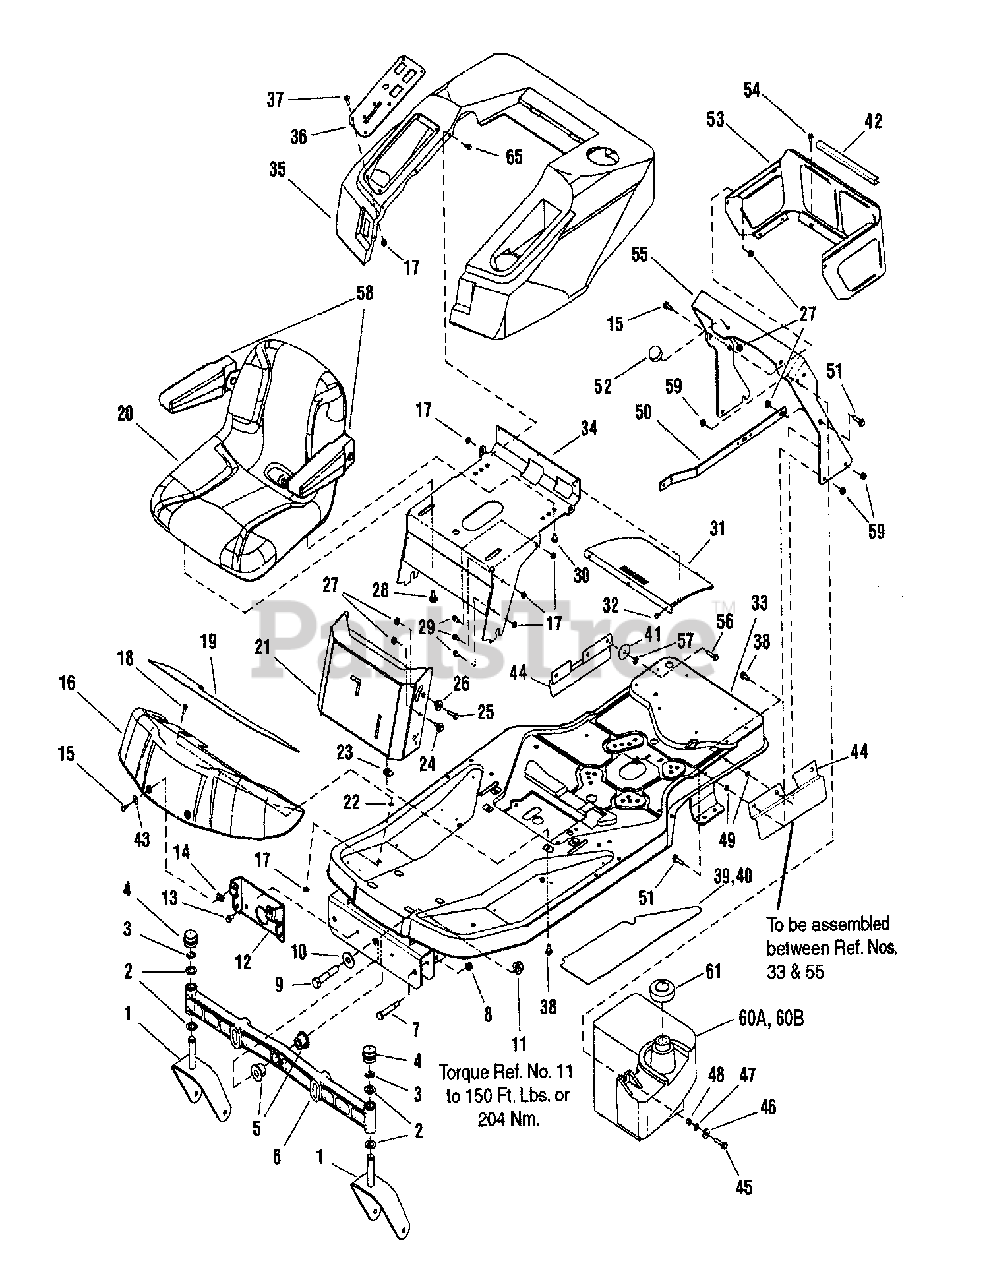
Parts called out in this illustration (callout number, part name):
1	WELDMENT, Caster Yoke & Spindle- Black
2	WASHER, .75 ID x 1.60 OD x .05 Thick Flat (Black)
3	KLIPRING, External for .750 Dia. Shaft
4	CAP, Hub 1.481 I.D. x .62 Long Red Poly
5	BUSHING, Axle Pivot PM Regent Yellow
6	AXLE, Front Iron Casting Machined ZT 2007
7	SHOULDER BOLT, 3/8-16 x 3" Long .50 Sh GR5 Black
8	NUT, 3/8-16 Hex Flange Nyloc
9	SCREW, 5/8-11 x 3-1/4" Hex Head Cap, GR5 Yellow
10	WASHER, 0.64 I.D. x 1.75 O.D. x .11 Thick, Black
11	NUT, Hex Flange 5/8-11 Two Way Lock Yellow
12	BRACKET, Footrest Support, 12 Ga Sears- Black
13	SCREW, 5/16-18 x .62 Taptite
14	SPEED NUT, 1/4-20 Lug Type .025/.150 Black
15	SCREW, 5/16-18 x 1" Hex Head Cap
16	PANEL, Footrest, 18 Ga ZT 7000 Gloss Orange
17	NUT, 1/4-20 Hex Flange Nyloc Black
18	BOLT, 1/4-20 x 2" Round Head Short Square Neck, GR5 Black
19	PAD, Footrest Center Black Vinyl Sears
20	ASSEMBLY, Seat w/Arm Rests ZTR Sears
21	PANEL, Front - Manual Brake & Deck Lift
22	RETAINER, 1/4" Bolt
23	SPEED NUT, 5/16 -18 Lug Type .025/.150 B
24	SHOULDER BOLT, 5/16-18
25	BOLT, 5/16-18 x 1-1/4" Round Head Short Square Neck GR5 Black
26	PIVOT, Hood (Powdered Metal)
27	NUT, 5/16-18 Hex Flange Lock, Small - Black
28	BOLT, 5/16-18 Idler Pivot
29	SCREW, 1/4-20 x 5/8" Hex Whiz Lock Flange
30	SCREW, 5/16-18 x 3/4" Hex Flange Lock Dog Point
31	SCREEN, Deck Top
32	RIVET, .188 x .617 Large Flange
33	WELDMENT, Frame- 33" ZT
33	WELDMENT, Frame- 42" & 50" ZT (Black)
34	SUPPORT, Seat Deck 12 GA ZTS Sears-Black
35	SEAT DECK, Orange Poly Sears ZTS
36	PLATE, Control 12 GA ZTS 2007- Black
37	SCREW, 1/4-20 x 3/4" Truss Head Torx Black
38	BOLT, 5/16-18 x 1" Hex Flange Lock YZ
39	PAD, Footrest RH Black Vinyl w/Adhesive Sears
40	PAD, Footrest LH Black Vinyl w/Adhesive Sears
41	WASHER, .375 Flat (0.41 I.D. x 1.50 O.D. x .25 Thick) Black
43	WASHER, 5/16" External Tooth Lock Washer Yellow
44	GUARD, Debris 12 Ga Sears ZTR 2007- Black
45	SCREW, 5/16-18 x 1-1/2" Hex Head Cap, GR5 Black
46	WASHER, 5/16" Flat (.341 I.D. x 1.00 O.D. x .13 Thick) Black
47	WASHER 5/16" Internal/External Tooth Lock, BZ
48	SPACER, .316 x .375 x .300/.310
49	PUSH NUT, 5/16" Dia. Thread .625 O.D. Black (Pal)
50	STRAP, Fuel Tank Brace
51	SCREW, 5/16-18 x 1-1/4" Hex Head Cap, GR5 Black
52	BUMPER, Rubber 1.50 DIA 0.5 Thick Sears
53	SHROUD, Rear 20 GA ZTR 14+16, Cor Black
54	SCREW, 1/4-20 x 1/2" Hex Washer Head Screw Black (Taptite)
55	SUPPORT, Seat Deck .250 Thick Sears- Black
56	SCREW, 3/8-16 x 1-1/4" Hex Head Cap, GR5 Black
57	PUSH NUT, .375 Dia. Thread .781 O.D. Black (Pal)
58	KIT, Arm Rest L.H. & R.H.
59	NUT, 5/16-18 Hex Flange Nyloc
60A	ASSEMBLY, Fuel Tank (incl. below items 61, 63 & 64)
60B	ASS'Y, Fuel Tank (incl. below items 61 through 64)
61	ASSEMBLY, Fuel Cap (Vented)
65	SCREW, 1/4-20 x 3/4" Hex Flange Lock Black
